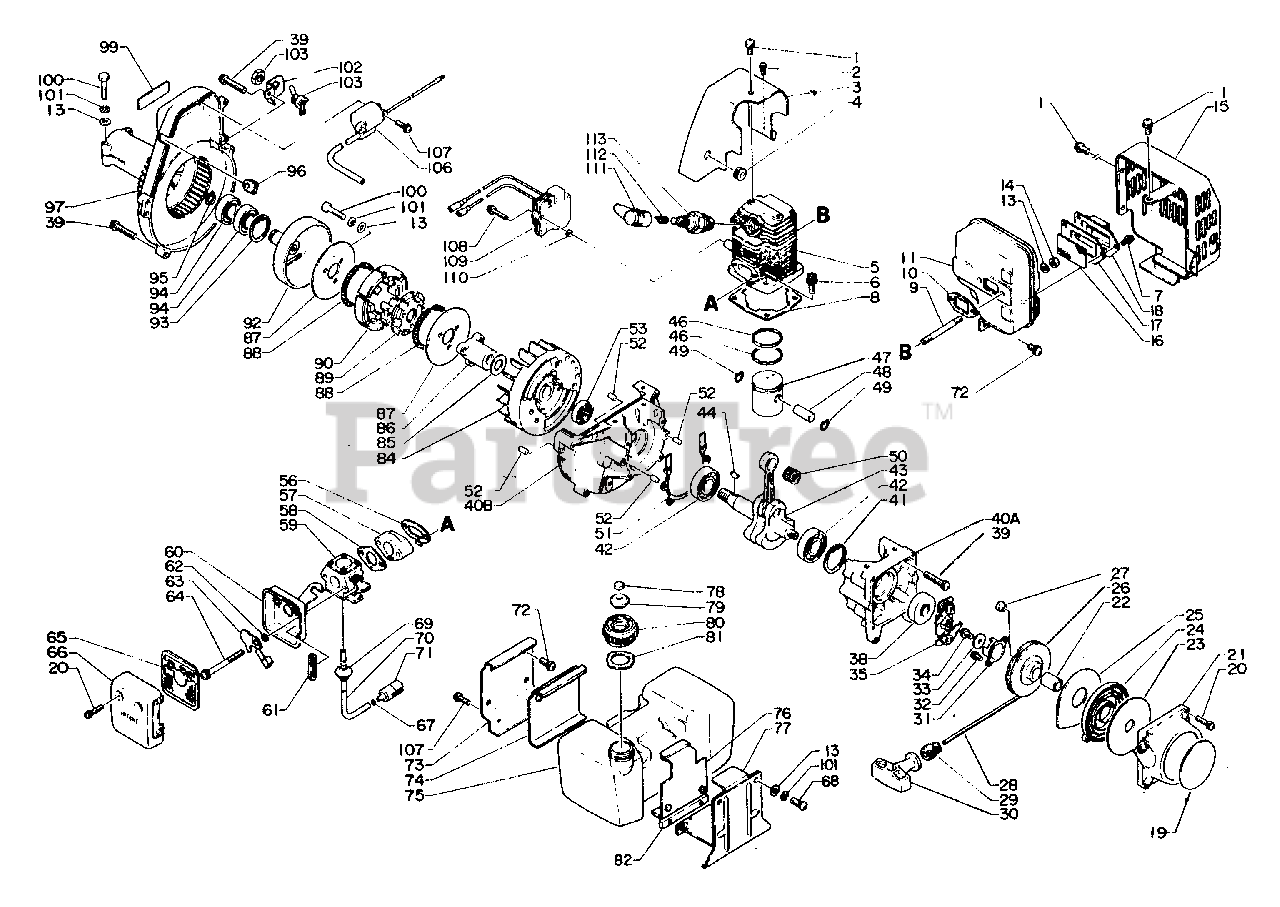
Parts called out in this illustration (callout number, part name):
1	SCREW - 5X10
2	SCREW - 4X10
3	COVER, ENGINE
5	CYLINDER
6	SCREW - 5X20
7	SCREW - 4X8
8	GASKET, CYLINDER
10	GASKET, EXHAUST
13	WASHER - 5
14	LOCKNUT - 5
15	COVER, EXHAUST
16	SCREEN, SPARK ARRESTOR
17	GASKET, EXHAUST
18	GUIDE, EXHAUST
19	LABEL - ECHO
20	SCREW - 4X20
21	CASE, STARTER
23	PLATE, STARTER
24	SPRING, REWIND
25	PLATE, STARTER
26	REEL, ROPE
27	RETAINER, ROPE
28	ROPE, STARTER - 3.5X850
29	GUIDE, ROPE
30	GRIP, STARTER
31	CATCHER, PAWL
32	SCREW - 4X8
33	WASHER - 5
34	SCREW - 5X10
35	STARTER PAWL ASSY
38	SEAL, OIL
39	SCREW - 5X30
40	CRANKCASE KIT
40A	CRANKCASE KIT
40B	CRANKCASE KIT
41	RING, RETAINING - 35
42	BEARING, BALL - 6202
43	CRANKSHAFT ASSY
46	RING, PISTON
47	PISTON
48	PIN, PISTON
49	RING, RETAINING - 8
50	BEARING, NEEDLE
51	GASKET, CRANKCASE
52	PIN - LOCATING
53	SEAL, OIL
56	GASKET, INTAKE
57	INSULATOR, INTAKE
58	GASKET, INTAKE
59	CARBURETOR WA-106
60	CASE, AIR FILTER
62	WASHER - 5
63	SHUTTER, CHOKE
64	SCREW - 5X60
65	FILTER, AIR
66	COVER, AIR FILTER
67	CLIP
68	SCREW - 5X14
70	PIPE - 3X5X195 -- BLACK
71	FILTER, FUEL
72	SCREW - 5X14
73	BRACKET, FUEL TANK
74	CUSHION
75	TANK, FUEL
77	BRACKET
80	CAP
81	GASKET, CAP
82	SPACER
84	FLYWHEEL
85	WASHER
86	ADAPTOR
87	PLATE, CLUTCH
88	SPRING, CLUTCH
89	HUB, CLUTCH
90	SHOE, CLUTCH
92	DRUM, CLUTCH
93	RING, RETAINING - 35
94	BEARING, BALL - 6203
95	RING, RETAINING - 15
97	CASE, FAN
98	SCREW - 5X25
99	LABEL - MODEL
100	BOLT - 5X25
101	LOCKWASHER - 5
102	BRACKET, SWITCH
103	IGNITION SWITCH KIT
106	COIL, IGNITION
107	SCREW - 4X14
108	SCREW - 4X22
109	COIL, IGNITION
111	CAP, SPARK PLUG
112	TERMINAL, SPARK PLUG CAP
113	SPARK PLUG -- BPM-7A
